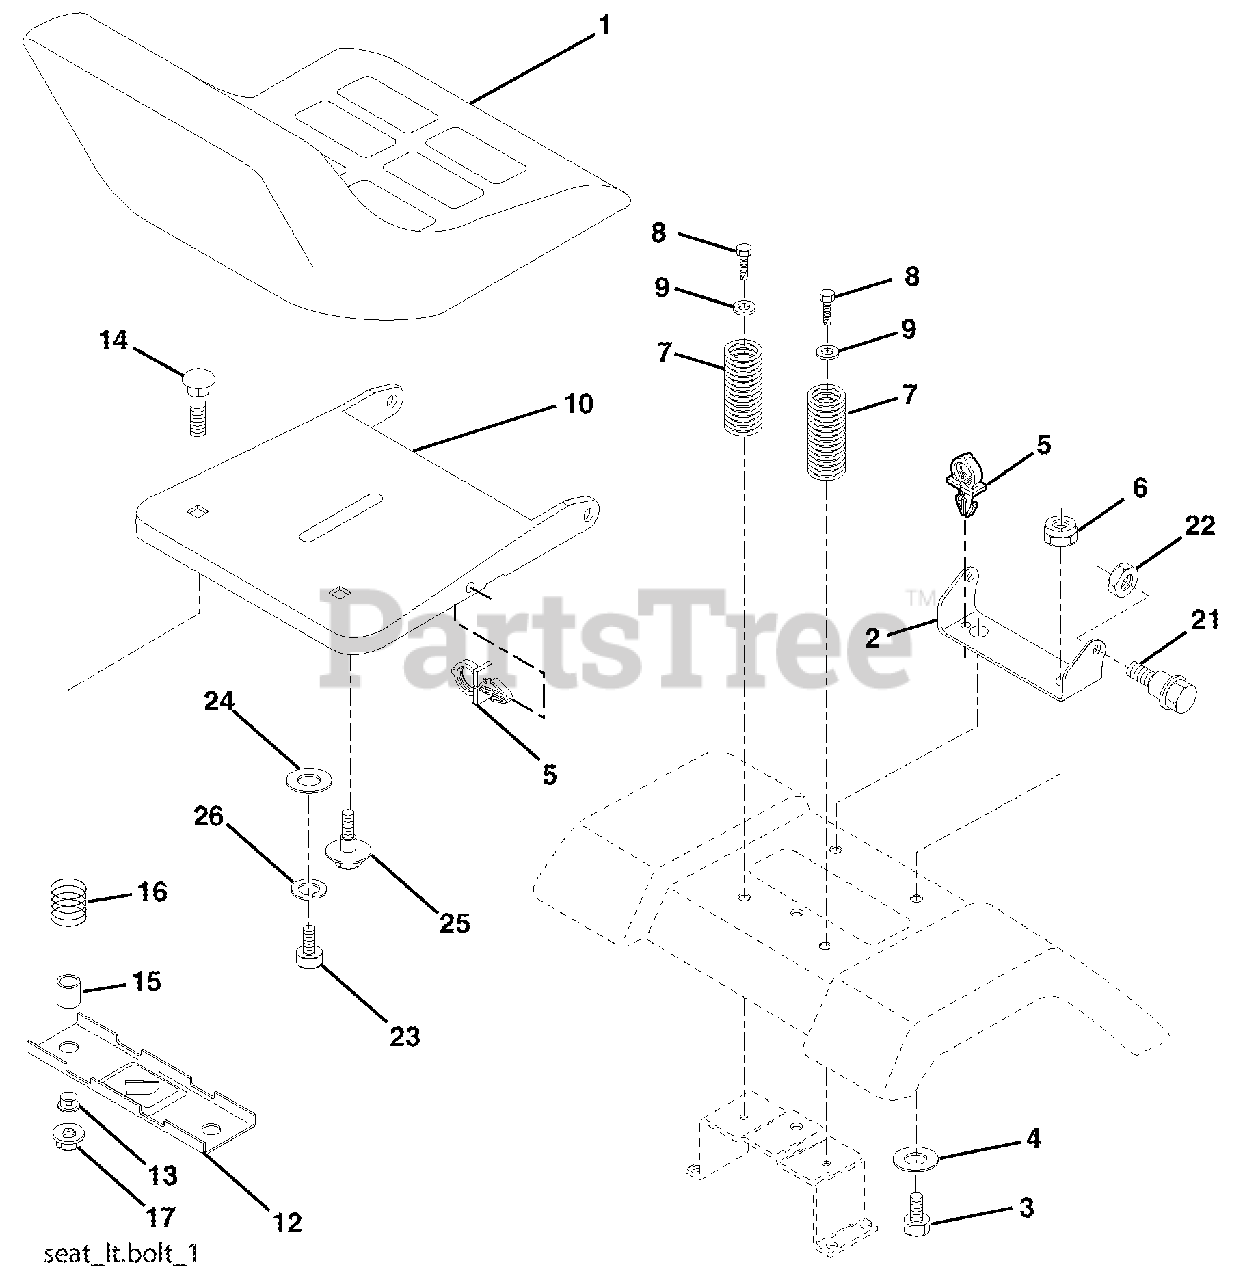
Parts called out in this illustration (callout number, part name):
1	Seat
2	Bracket Pnt Pivot Seat (blk)
3	Bolt
4	Washer 13/32 x 1 x 10 Ga
5	Clip Push-In Hinged
6	Nut
7	Spring Seat Cprsn 2 250 Blk Zi
8	Screw 3/8-16 x 1.5
9	Washer 13/32 x 1 x 14 Ga
10	Pan Pnt Seat (blk)
12	Bracket Pnt Mounting Switch
13	Bushing Snap Blk Nyl 50 Id
14	Bolt Rdhd Sht Nk 1/4-20 x 1-1/2
15	Spacer Split 28 x 96 Yel Zinc
16	Spring Cprsn 1 27 Blk Pnt
17	Nut Lock 1/4 Lge Flg Gr 5 Zinc
21	Bolt Shoulder 5/16-18 Unc Blkz-2A
22	Nut
23	Bolt Hex Black
24	Washer 17/32 x 1-3/16 x 12 Ga
25	Bolt Shoulder 5/16-18 x 62
26	Lockwasher
